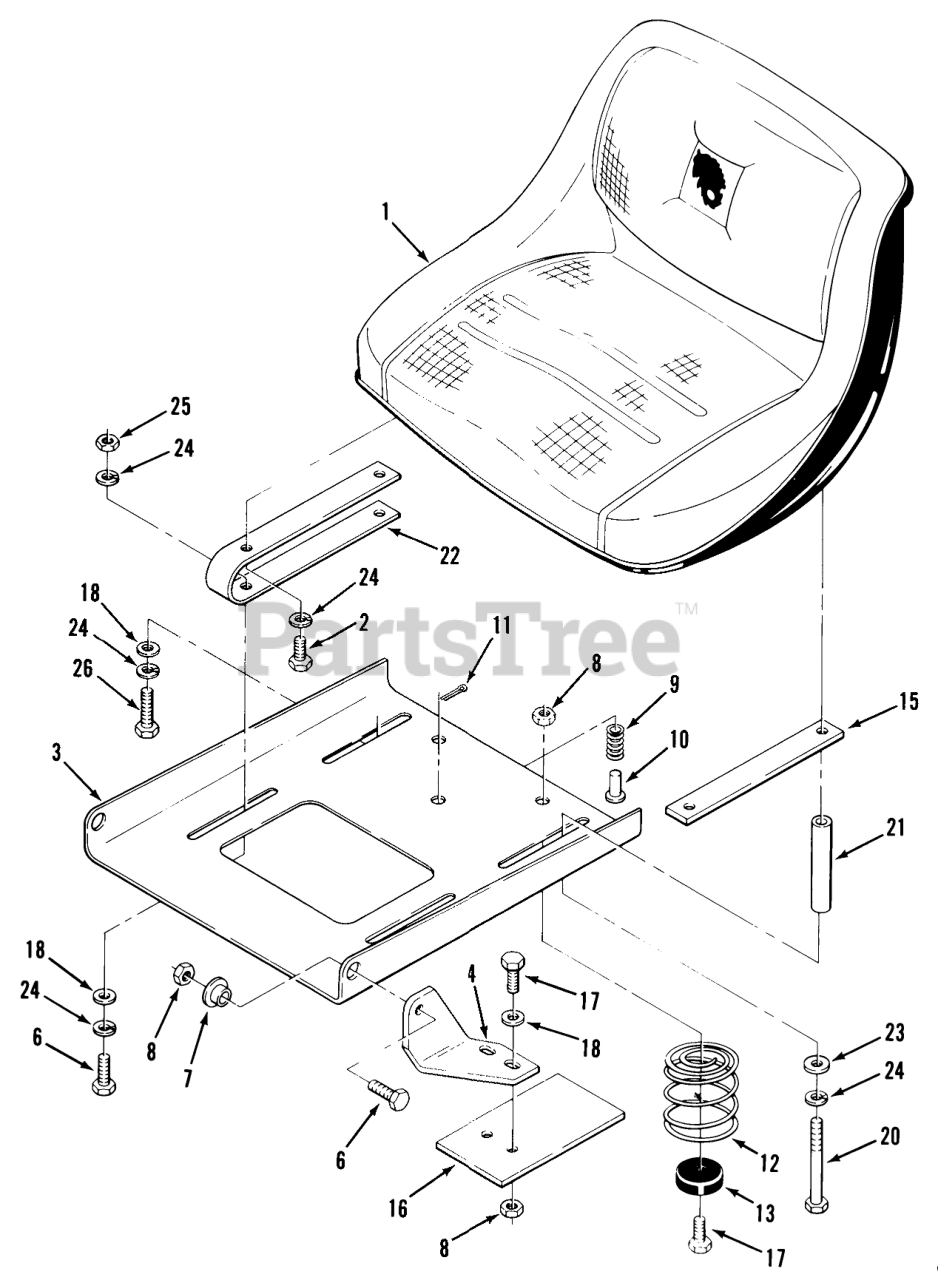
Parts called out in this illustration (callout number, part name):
1	ASSY-SEAT
1	Seat
2	Bolt
3	PLATE-SEAT PIVOT B
4	Bracket-Pivot RH
4	BRACKET-PIVOT L.H B
6	HHCS
7	BUSHING
8	Nut
9	SPRING-SEAT SWITCH
11	Cotter Pin
12	SPRING-SEAT NYLON
13	BUMPER
15	BAR SEAT SUPPORT B
16	PLATE R
17	Bolt
18	WASHER 5/16 SAE
20	Pin-Cotter
21	SPACER SEAT B
22	SPRING-SEAT B
23	Collar
24	Lockwasher
25	Nut
26	Bolt
